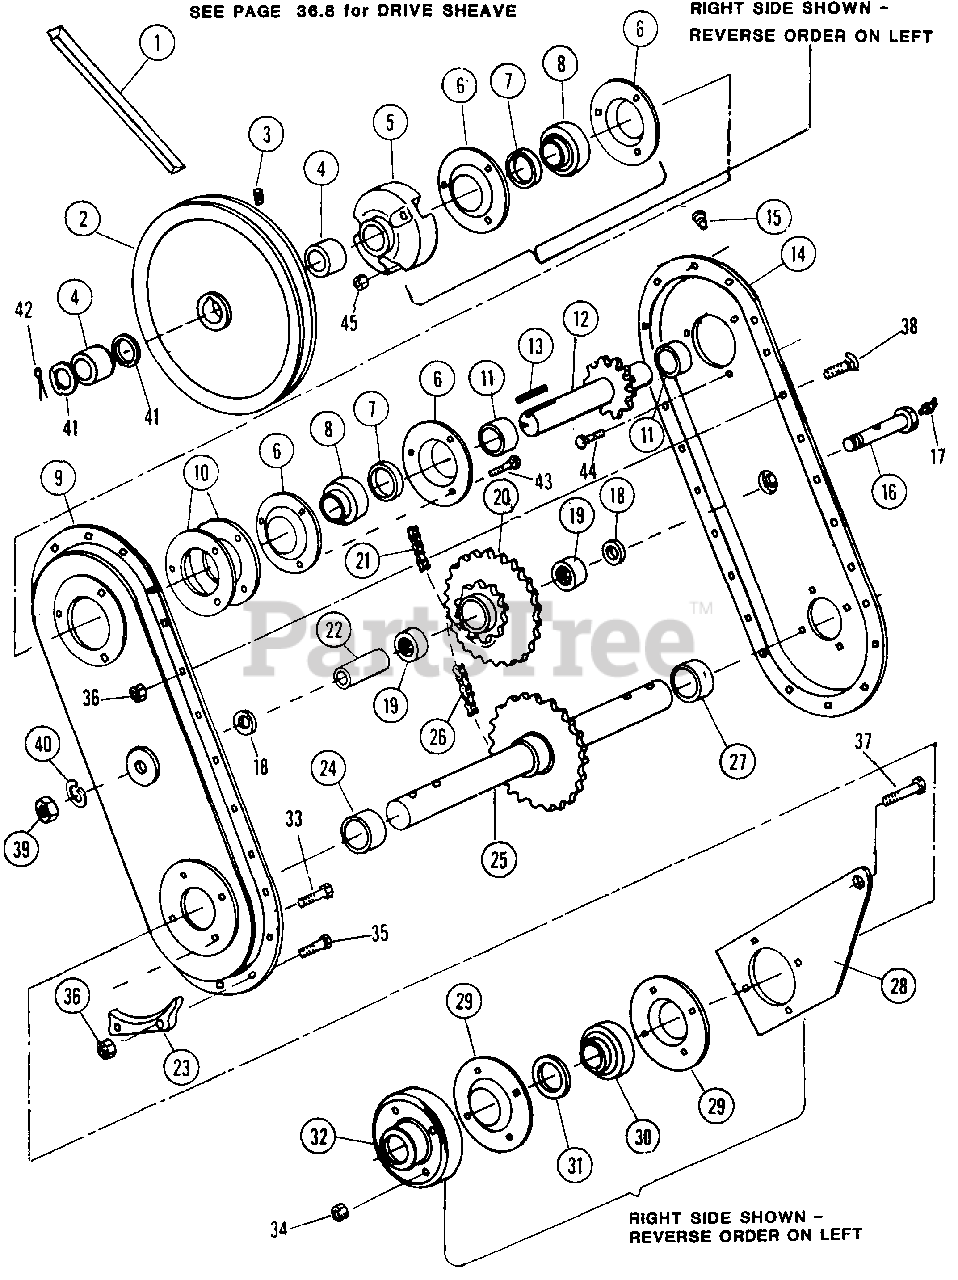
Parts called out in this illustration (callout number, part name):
1	BELT, DRIVE
2	SHEAVE, DRIVEN
3	SETSCREW, 5/16 x 1/2 HEX SOCKET
4	SPACER, UPPER SHAFT 1.05" DI x 1.312" OD x .41"
5	HUB, PIVOT
6	FLANGETTE, 3-HOLE
7	LOCK-COLLAR, BEARING
8	BEARING, SPROCKET SHAFT
9	HOUSING, CHAIN CASE - RIGHT HAND
10	SPACER, UPPER RING
11	SPACER, UPPER SHAFT 1.05" x 1.31" x .3"
12	SHAFT & SPROCKET - UPPER
13	KEY, SQUARE, 1/4X1
14	HOUSING, CHAIN CASE - LEFT HAND
15	COVER, OIL HOLE
16	BOLT, SPECIAL 1/2-20x3.5 Drilled 1/4 for Fitting
17	FITTING, GREASE 1/4-28 45 Deg. W/Check Ball
18	WASHER, Bronze Thrust .765" x 1.562" x .092"
19	BEARING, NEEDLE SEALED .75" ID x 1" OD x .688"
20	CLUSTER SPROCKET
21	CHAIN, UPPER ASA #50, 35 Pitches
22	BEARING, TUBE
23	WEAR-BAR
24	SPACER, LONG 1.38" x 1.66" x 1.09"
25	SHAFT, TINE
26	CHAIN, TINE SHAFT DRIVE ASA #60 36 Pitches
27	SPACER, SHORT 1.38" x 1.66" x .385"
28	PLATE, ATTACHING
29	FLANGETTE, 4-HOLE
30	BEARING 1.25" ID
31	LOCK-COLLAR, TINE SHAFT BEARING
32	CAP, BEARING GUARD
33	BOLT, 3/8 x 1-1/2 CARRIAGE
34	LOCKNUT, 3/8-16 HEX
35	BOLT, 1/4 x 2 HEX HEAD
36	LOCKNUT, 1/4-20 HEX
37	BOLT, 1/4 x 4 HEX HEAD
38	BOLT, 1/4 x 1/2 CARRIAGE
39	NUT, 1/2-20 HEX
40	LOCKWASHER
41	WASHER, SPECIAL
42	PIN, 1/8 x 1-1/2 COTTER
43	BOLT, 5/16-18 x 2 CARRIAGE
44	BOLT, 5/16-18 x 1-1/2 CARRIAGE
45	NUT, 5/16-18 HEX.LOCK
